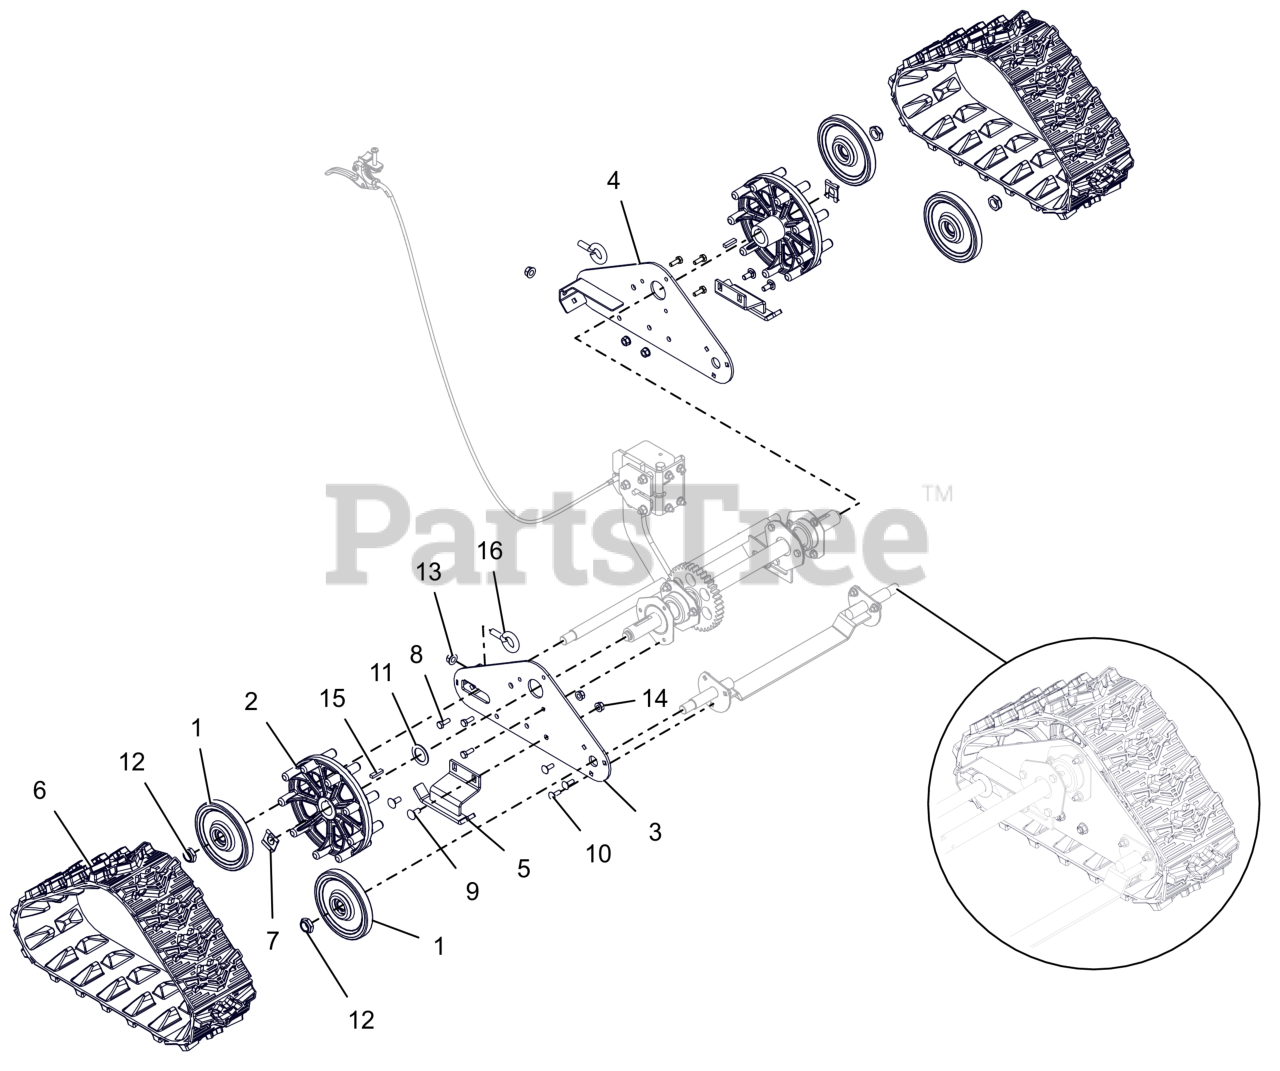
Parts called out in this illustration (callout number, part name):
1	WHEEL, BOGIE - SINGLE BEARING
2	WHEEL, MACHINED DRIVE
3	PLATE, SIDE-COMPACT RH WLDMT
4	PLATE, SIDE-COMPACT LH WLDMT
5	RUNNER, GUIDE-CMPT TRACK BLACK
6	TRACK, RUBBER COMPACT
7	CLIP, SNAP .625 DIA
8	BLT, HEX .25-20X.75 G5 ZCC
9	BLT,RHSN .31-18X.75 G5 ZCC
10	BLT, RHSN .25-20X.750 G5 ZCC
11	WSHR, FLT 1.010X1.505X.062 ZCC
12	NUT, NYL LK .625-18 ZCC
13	NUT-LK-CTR-FLG .375-16 GF ZCC
14	NUT-LK-TOP-FLG .312-18 GF ZCC
15	KEY-RECT .25X.188X1.00
16	BLT-EYE .375-16X.880 YWZC
